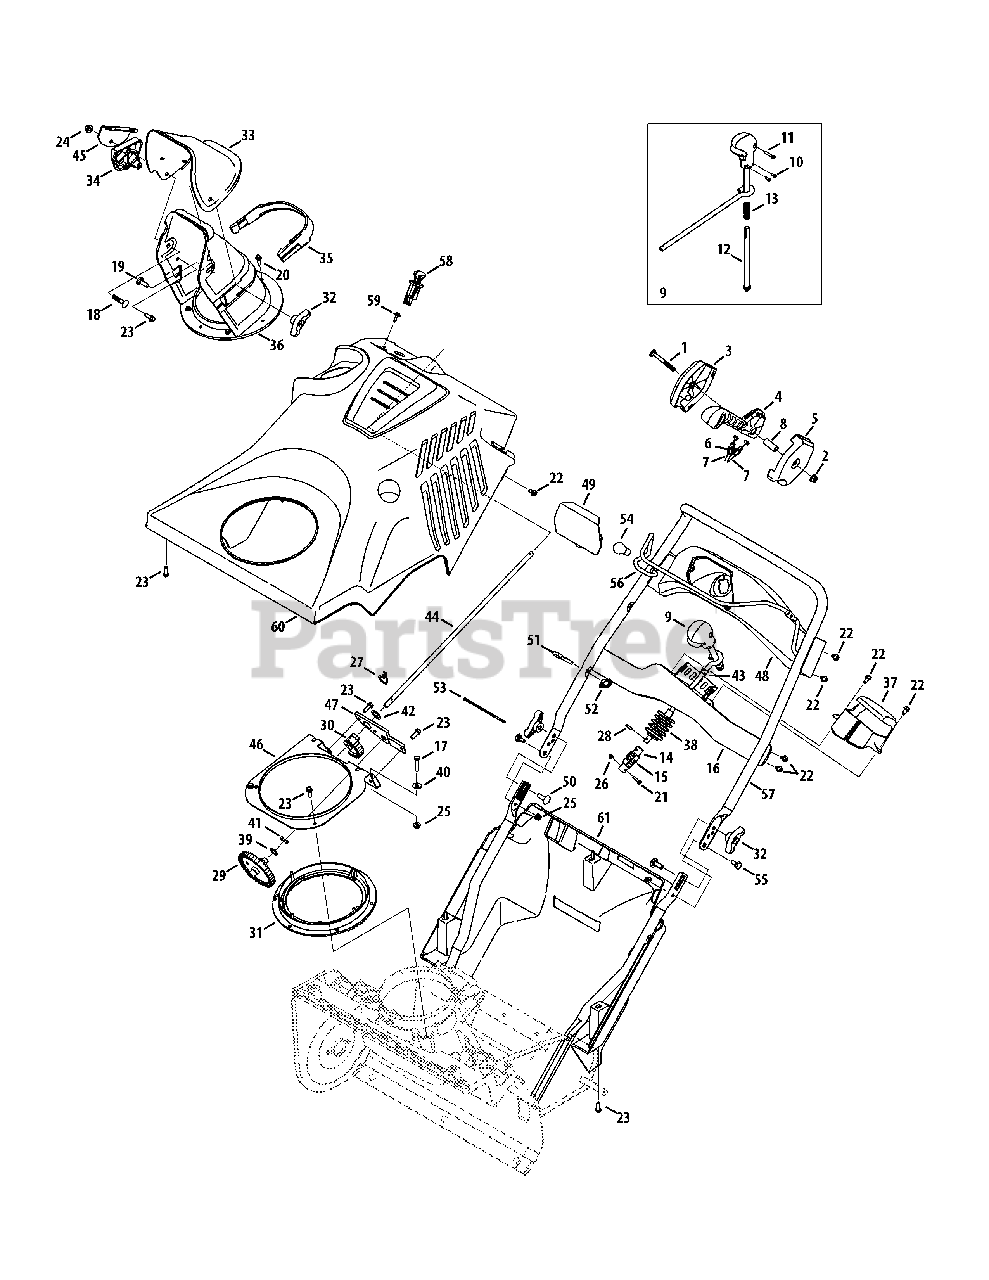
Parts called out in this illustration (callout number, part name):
1	Carriage Bolt, 5/16-18 x 2.5
2	Flange Lock Nut, 5/16-18
3	Chute Control Panel
4	Cable Handle Guide
5	Chute Control Panel, Inner
6	Cable Clip
8	Spacer, .325 ID x .496 OD x 1.34
9	Chute Control Assembly
10	Screw, #6 x .375
11	Screw, #8 x 1.00
13	Spring, .460 OD x 1.469
14	Joint Block Assembly
15	Roll Pin, 3/16 Dia. x 1.1 LG.
17	Hex Screw, 1/4-20 x 1.25
18	Carriage Bolt, 5/16-18 x 1.00
19	Carriage Bolt, 5/16-18 x 1.00
20	Hex Washer Screw, 1/4 x .750
21	Screw, #8-32 x .875
22	Hex Washer Screw, 1/4-20 x .500
23	Screw, Hi-Lo:1/4-15, 0.75
24	Flange Lock Nut, 5/16-18
25	Flange Lock Nut, 1/4-20
26	Hex Lock Nut, #8-32
27	Internal Cotter Pin, .125 x 2.5
28	Pin, .156 x .875
29	Bevel Gear, 40T/11T
30	Spur Gear, 32T
31	Bevel Gear, 95T
32	Wing Knob, 5/16-18
33	Upper Chute
34	Cable Guide
35	Chute Plug
36	Lower Chute
37	Chute Cover
38	Bellows-Chute Crank
39	Flat Washer, .510 x .750 x .033
40	Flat Washer, .28 x .74 x .063
41	Wave Washer, .531 x .781 x .013
42	Flat Washer, .75 x 1.00 x .06
43	Plastic Bushing, .380 ID
44	Chute Rod
47	Gear Mounting Plate
48	Handle Panel Assembly
49	Handle Panel Lens
50	Carriage Screw, 5/16-18 x 1.00
51	Eye Bolt, 1/4-20
52	Handle Knob, 1/4-20
53	Cable Tie
54	Lamp
55	Shoulder Screw, .375 x .148 x 1/4-20
56	Auger Bail
57	Upper Handle
58	Ignition Switch Assembly
59	Hex Washer Screw, 10-16 x .625
60	Top Cover
61	Bottom Cover
